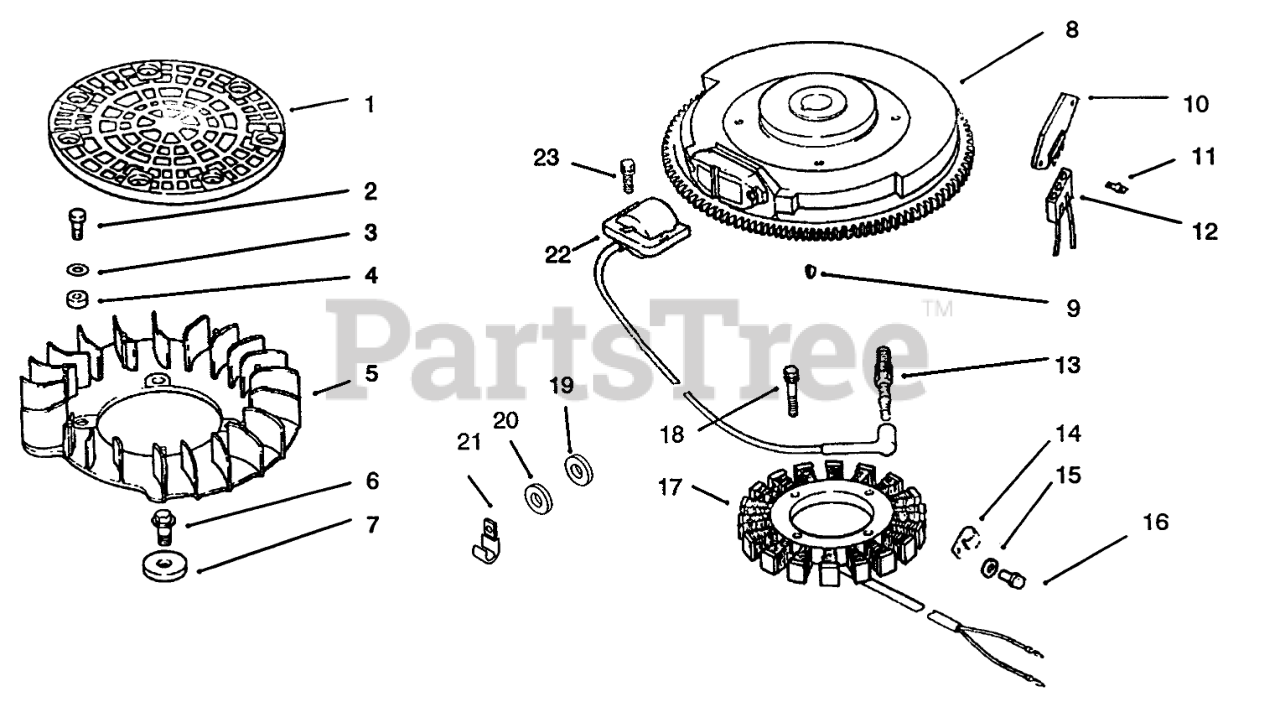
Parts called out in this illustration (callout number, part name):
1	Screen-Grass (Only On: 72103, 72083)
2	Screw M4x0.7x24 (Only On: 72103, 72G83)
3	Washer-Flat (Only On: 72103, 72083)
4	Spacer-Fan (Only On: 72103, 72083)
5	Fan (Only On: 72103, 72083)
6	Screw M6x1.0x16 (Only On: 72103, 72083)
7	Spacer-Fan (Only On: 72103, 72083)
8	Flywheel ASM (Only On: 72103, 72083)
9	Key (Only On: 72103, 72083)
10	Rectifier-Regulator (Only On: 72103, 72083)
11	Screw-Phillips (Only On: 72103, 72083)
12	Connector-Regulator (Only On: 72103, 72083)
13	Spark Plug (Only On: 72103, 72083)
14	Clip-Stator Harness (Only On: 72103, 72083)
15	Washer-Flywheel Screw (Only On: 72103, 72083)
16	Screw-Flywheel Mounting (Only On: 72103, 72083)
17	Stator-15 Amp (Only On: 72103, 72083)
18	Screw M5x0.8x25 (Only On: 72103, 72083)
19	Washer-Flat (Only On: 72103, 72083)
20	Washer-Flat (Only On: 72103, 72083)
21	Clip-Cable (Only On: 72103, 72083)
22	Module-Ignition (Only On: 72103, 72083)
23	Screw M5x0.8x20 (Only On: 72103, 72083)
